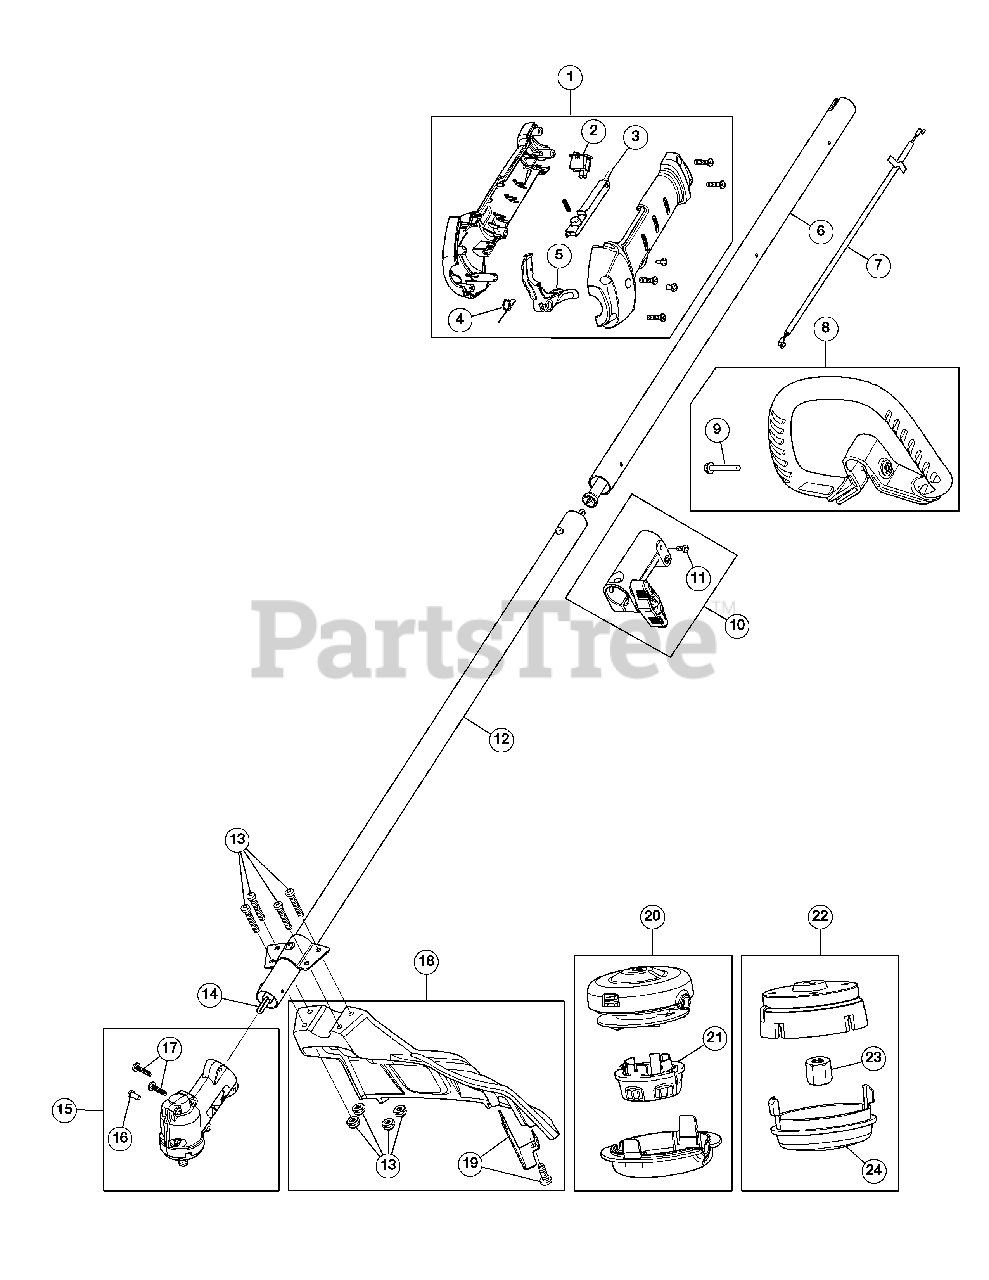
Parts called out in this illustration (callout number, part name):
1	Throttle Housing Assembly (Incl. 2 - 5)
2	Trigger Switch Assembly
3	Throttle Lock-out
4	Throttle Trigger Spring
5	Throttle Trigger
6	Upper Drive Shaft Assembly
7	Throttle Cable
8	D-Handle Assembly (Incl. 9)
10	Split Boom Coupler (Incl. 11)
11	Coupler Anti-Rotation Screw
12	Lower Drive Shaft Housing Assembly
13	Shield Mounting Screws and Nuts
14	Lower Flexible Drive Shaft
15	Gearbox Assembly (Incl. 16 - 17)
16	Gearbox Anti-Rotation Screw
17	Gearbox Mounting Hardware
18	Shield Assembly (Incl. 19)
19	Blade Assembly
20	Cutting Head Assembly (Incl. 21)
22	Aero Flex Cutting Head (Incl. 23 and 24)
24	Aero Flex Cap
